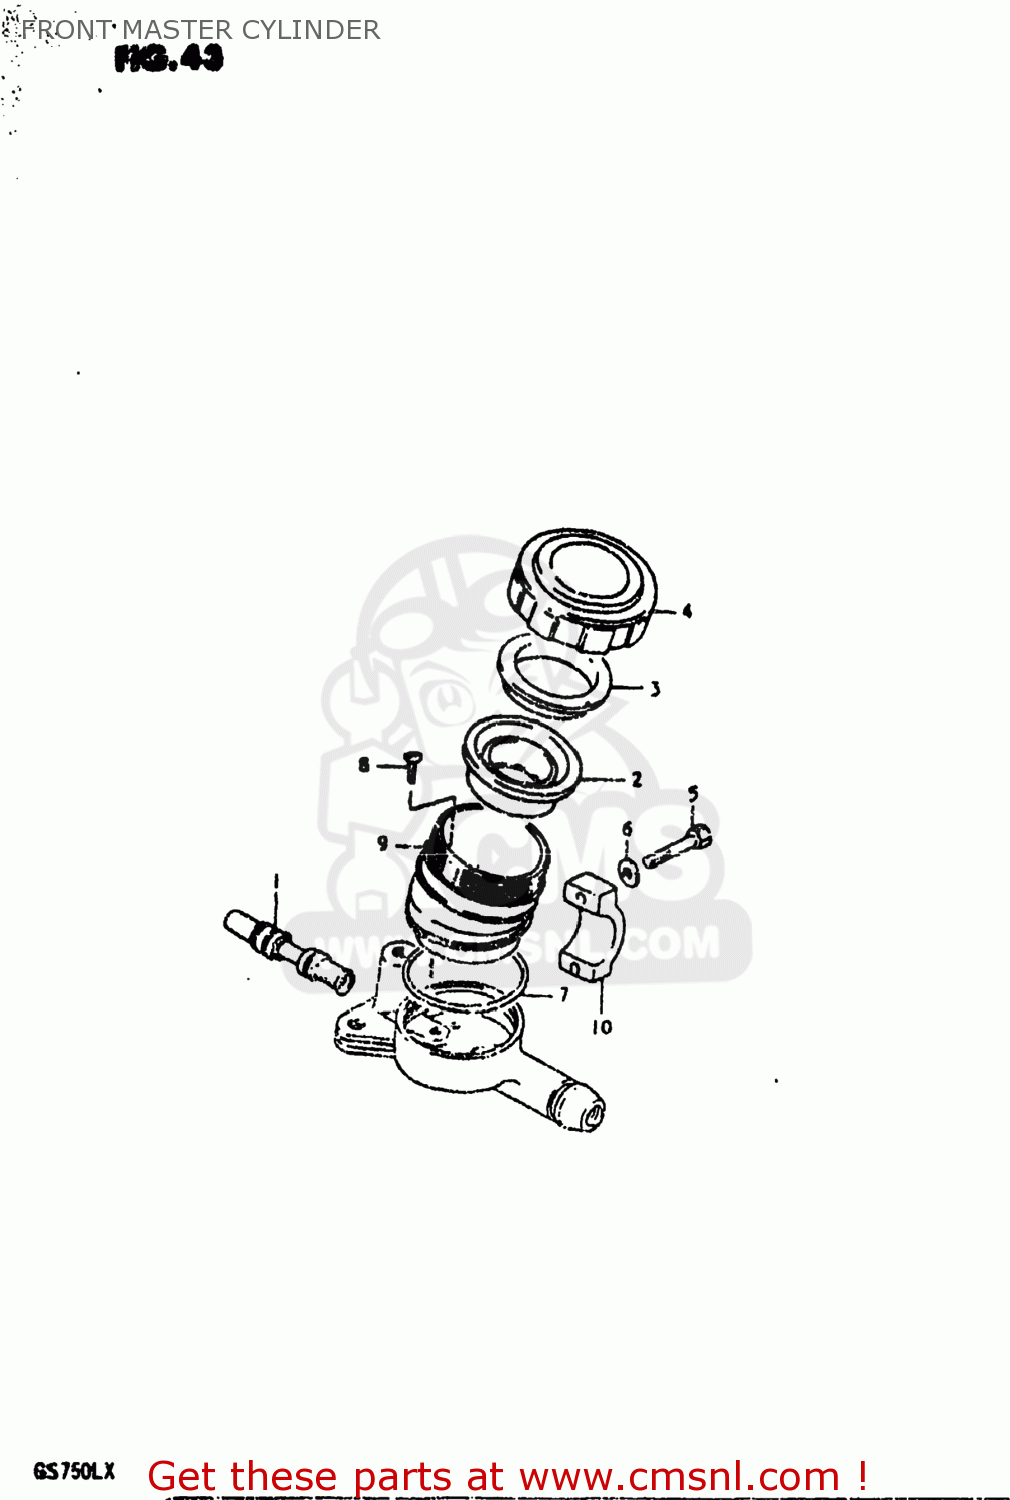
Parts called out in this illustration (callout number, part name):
1	PISTON & CUP SET
2	DIAPHRAGM
3	PLATE,DIAPHRAGM
4	CAP
5	BOLT
6	WASHER
7	O RING
8	SCREW,MASTER CYLINDER
9	RESERVOIR
10	HOLDER,MASTER CYLINDER
